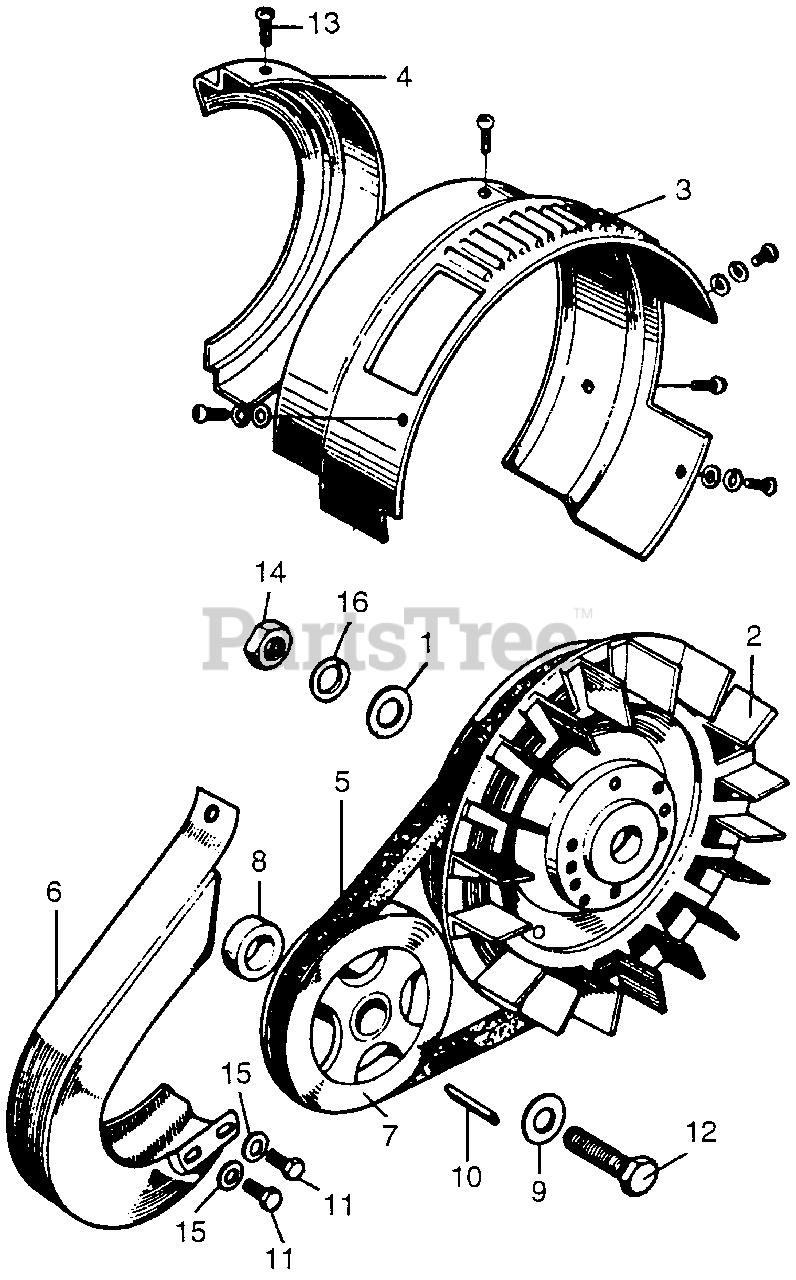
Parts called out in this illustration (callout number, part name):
1	WASHER, SPRING (12MM)
2	PULLEY ASSY., FAN
3	COVER, FAN *PB6M* (CRYSTAL BLUE METALLIC)
3	COVER, FAN *R8* (BRIGHT RED)
4	COVER, ALTERNATOR BELT (PB6M)
4	COVER, GENERATOR BELT *R8* (BRIGHT RED)
5	V-BELT (A-29) (NOT AVAILABLE)
6	COVER, BELT *NH2L* (CLOUD WHITE)
6	COVER, BELT *A03* (SILVER)
7	V-PULLEY (122DIA.) (NOT AVAILABLE)
9	WASHER (8MM)
10	KEY (5X5X33)
11	BOLT, HEX. (6X8)
12	BOLT, HEX. (8X20)
13	SCREW, PAN (6X8)
14	NUT, HEX. (12MM)
15	WASHER, PLAIN (6MM)
16	WASHER, PLAIN (12MM)
